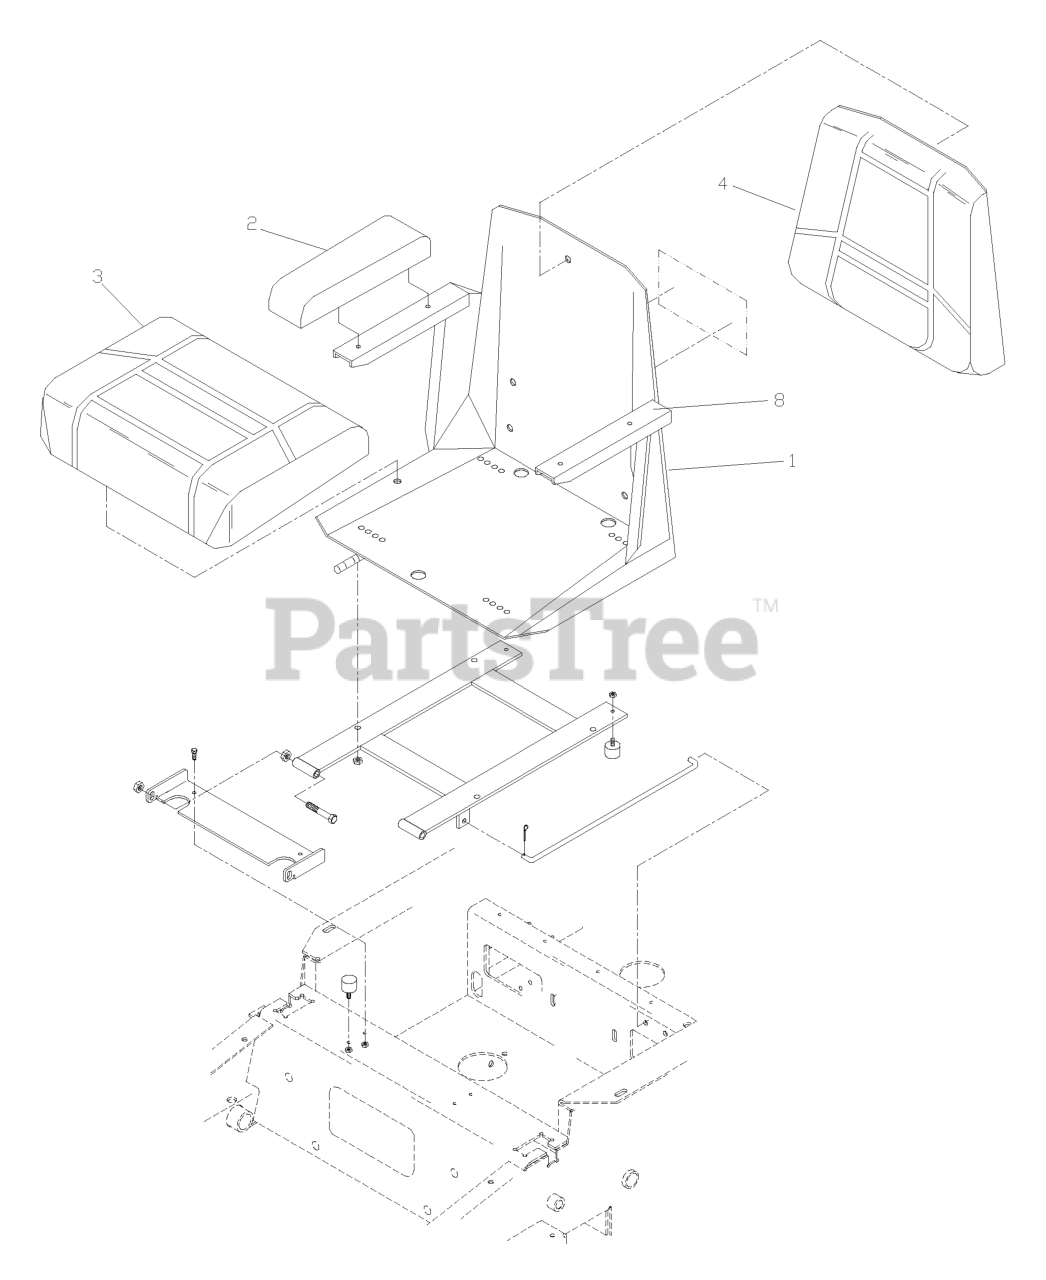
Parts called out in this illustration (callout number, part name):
1	SEAT, COMPLETE
2	ARM REST CUSHION
3	SEAT CUSHION
4	BACK CUSHION
5	SEAT SWITCH
6	SEAT RAILS
7	SEAT HARNESS
8	ARMREST BRACKET
